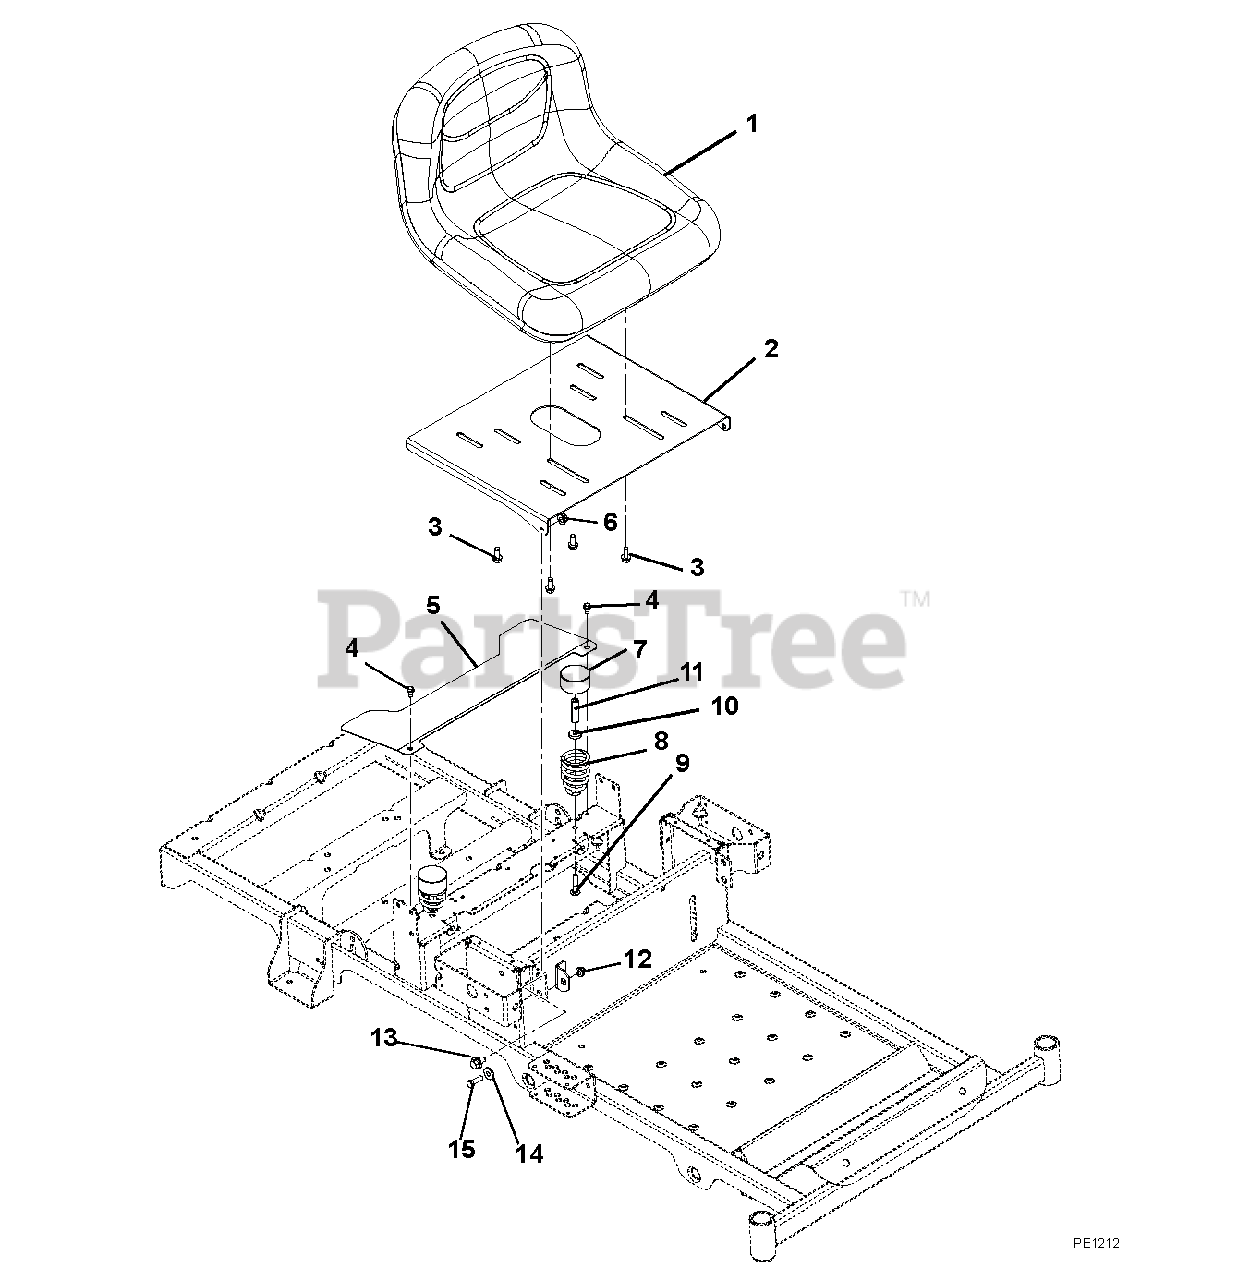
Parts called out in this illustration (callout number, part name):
1	SEAT-13" GREY
2	PLATE, SEAT
3	5/16-18X3/4 HX/W/HD WHIZ
4	@SCR-TAP .25-20X.50 HWH TR YWZ
5	GUARD, FAN
6	@NUT-LK-TOP-FLG .38-16 YWZC
7	HUB CAP
8	SPRING, SEAT
9	@BLT-RDHDSQNK .31-18X1.50 G5YZ
10	WSHR-FL-STL .328X.87X.179 YWZC
11	NUT, COUPLING 5/16-18 X 1 3/4
12	@NUT-LK-NYL-FLG .31-18 YWZC
13	BOLT-SHLDR .375-16X.150
14	BSHG, FLG .325X.499X.26X.88
15	@BLT-HEX .31-18X1.00 GR5 YWZC
